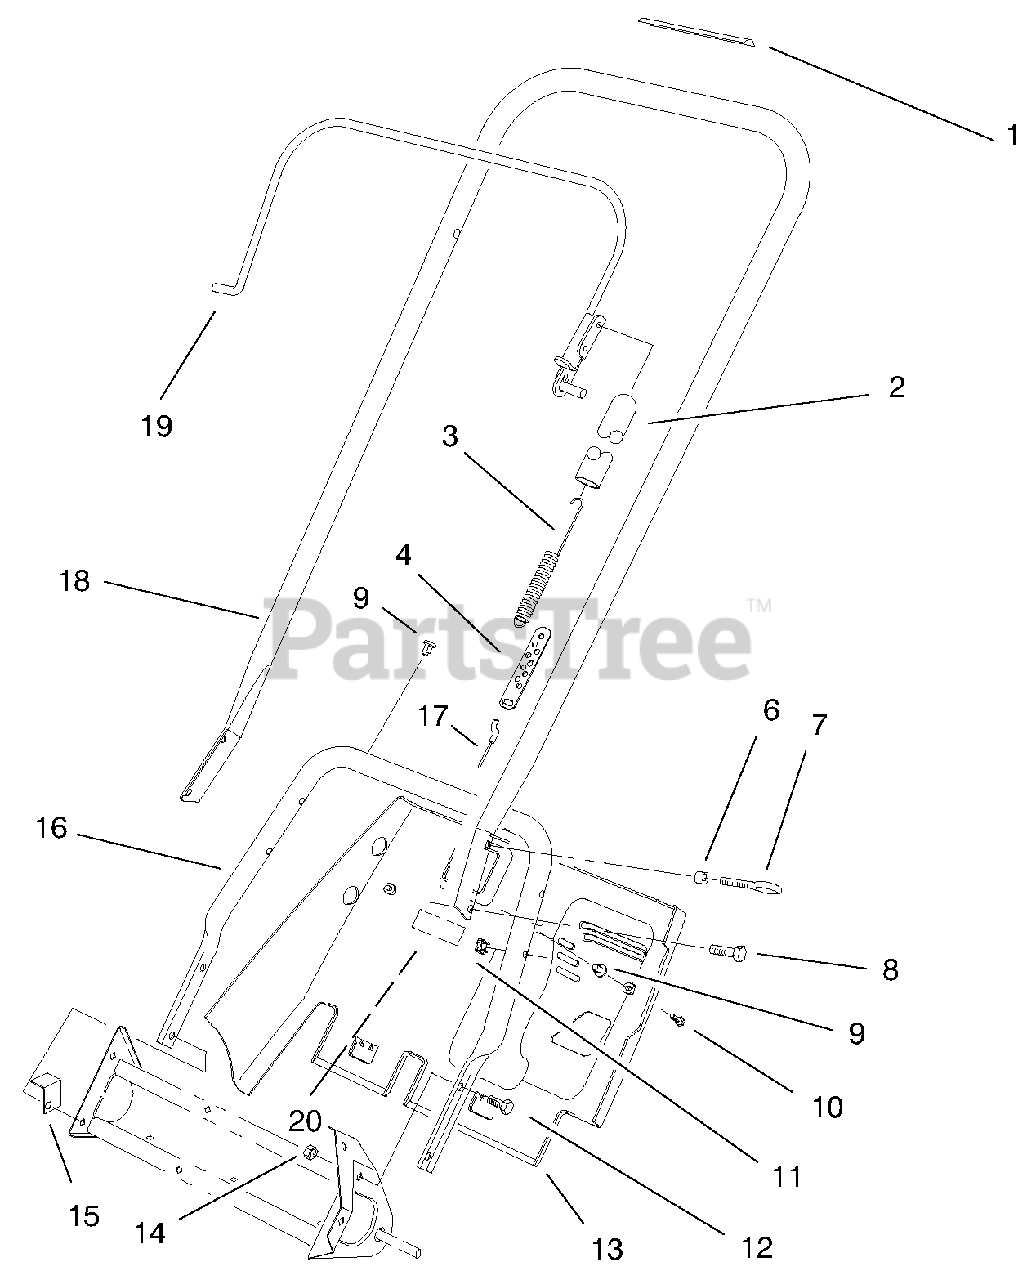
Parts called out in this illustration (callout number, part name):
1	Decal-Rotor Drive
2	Cover-Spring
3	Spring-Clutch
4	Adjuster-Cable
6	Spacer-Rotor Blade
7	Eyebolt
8	Screw-Slot Hex
10	Screw-Tf Acorn Hd
11	Nut-Speed
12	Screw-HH
13	Shroud-Lower
14	Nut-Lock
15	Bracket-Shroud
16	Tube-Handle
17	Cable-Clutch
18	Handle-Upper
20	Decal-Warning (Csa) (E)(Model 28222)
